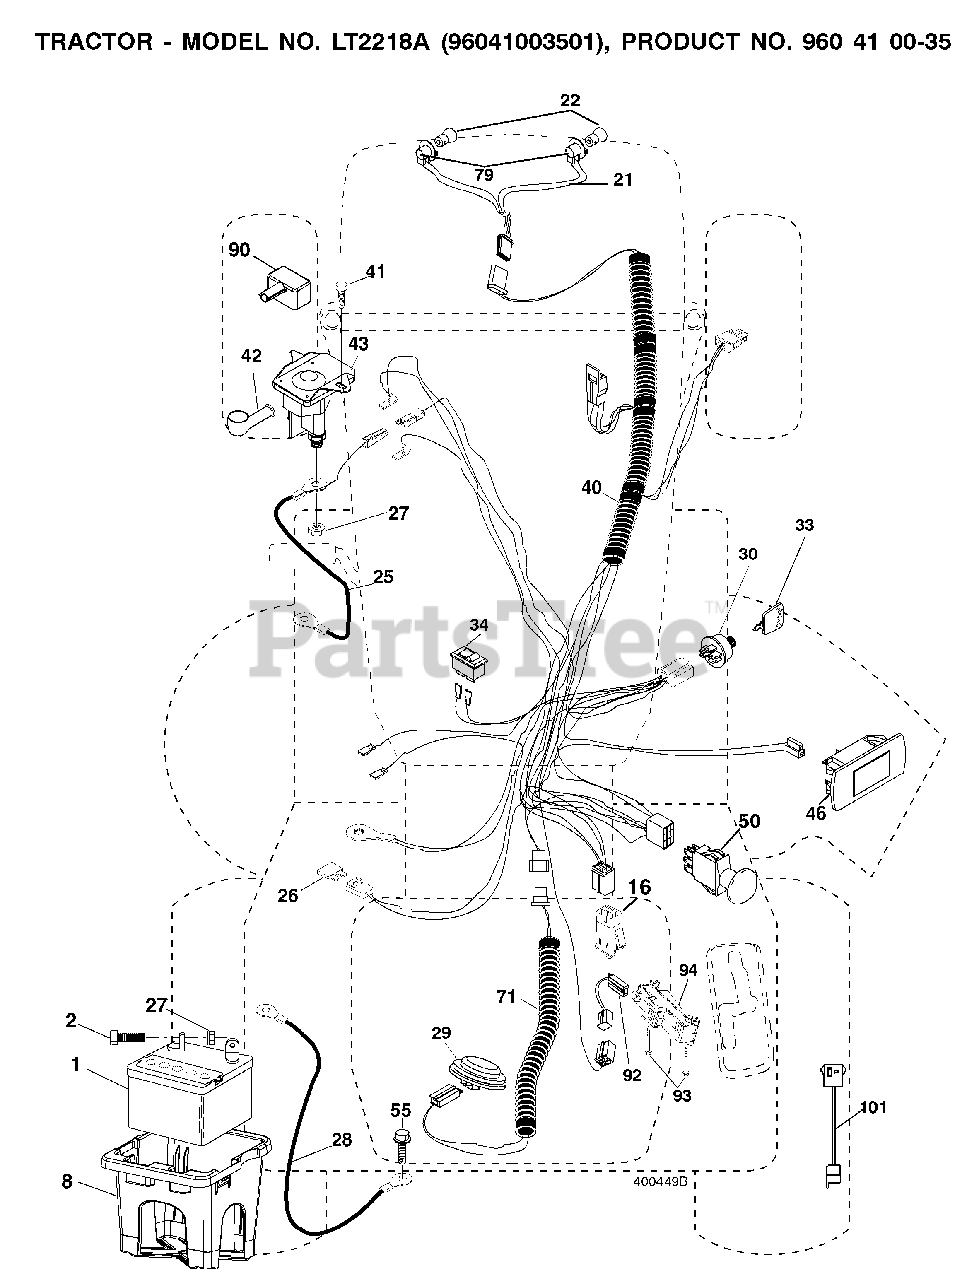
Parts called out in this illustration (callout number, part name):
1	BATTERY 12V .35 AMP
8	BOX.BATTERY.MNT.REAR.L
16	SWITCH INTERLOOK PUSH-IN
21	HARNESS.W/LIGHT SOCKET
22	LIGHTBULB
25	CABLE.START.RED.17.5".
26	FUSE 20AMP
27	NUT
28	CABLE.BLACK.18"REAR.BA
29	SWITCH.SEAT.DELTA.OPC.
30	SWITCH.IGN.DELTA.W.LGH.ROS
33	KEY MLD GEN DELTA
34	SWITCH LT
40	HARNESS.IGN.DASH.HUQ/P
41	SCREW
42	TERMINAL COVER
43	SOLENOID.W/BRASS.PLUNG
46	GUAGE.SRVCMNDR.HRMTR.
50	PTO SWITCH
55	SCREW 5/16"
71	HARNESS.IGN.CHASS.TEX.REAR.BAT
79	BULB HOLDER ASM.
90	COVER, TERMINAL BATTERY
92	HARNESS.PIGTAIL.CONSLE
93	SCREW.PLASTITE
94	MODULE.REVERSE.ROS
101	PIGTAIL.MATNLK.NEW.HAR
